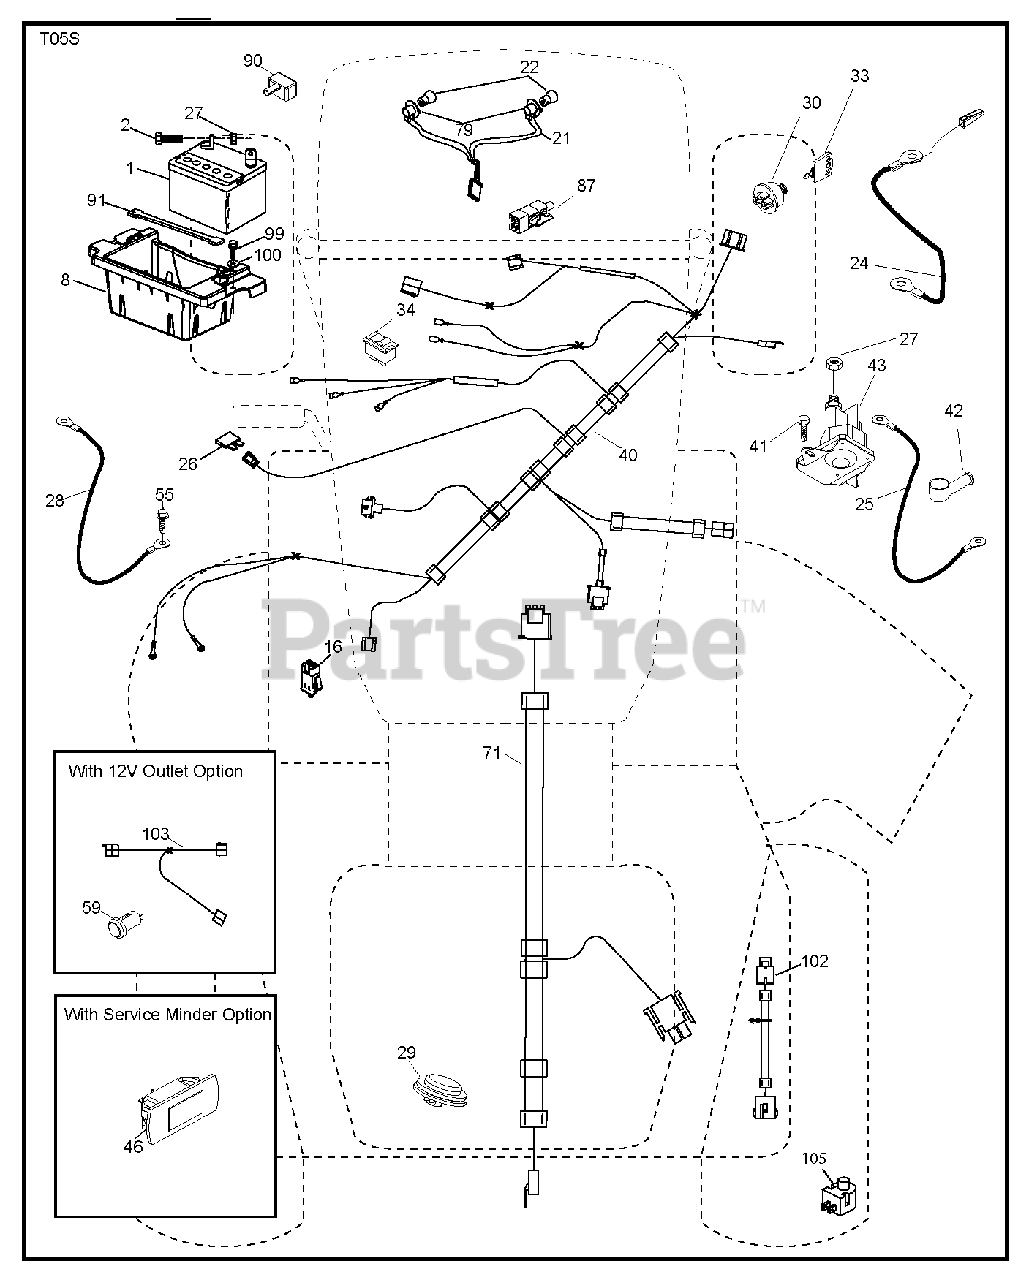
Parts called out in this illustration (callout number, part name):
1	REPL BY 532 12 38-99
8	BOX.BATTERY.MOUNT.FRONT.LT
16	SWITCH INTERLOOK PUSH-IN
21	HARNESS.LIGHT W/4152J BULBS
22	LIGHTBULB
24	CABLE.BATT.POS.WIRE.TG.DA SOL
25	CABLE.STARTER.6G.BL/RED.17.5
26	FUSE 20AMP
27	NUT
28	CABLE GROUND 6 GA 21" 90T BLK
29	SWITCH.SEAT.DELTA.OPC.
30	SWITCH.IGN.DELTA.W.LGH.ROS
33	KEY.CHAIN.BLISTER.PACK.GEN.INT
34	SWITCH LT
40	HARNESS IGN. DASH
41	SCREW
42	TERMINAL COVER
43	SOLENOID.W/BRASS.PLUNG
46	GUAGE.SRVCMNDR.HRMTR.
55	SCREW 5/16"
71	HARNESS-CHASSIS SUB
79	BULB HOLDER ASM.
87	SWITCH.INTRLCK.CLUTCH.
90	COVER.TERMINAL.BATTERY
91	STRAP, BATTERY MOUNT
99	SCREW HEXWSHR 1/4-20X3/4
102	HARNESS PIGTAIL PCH TEX ROS
105	REVERSE SWITCH
